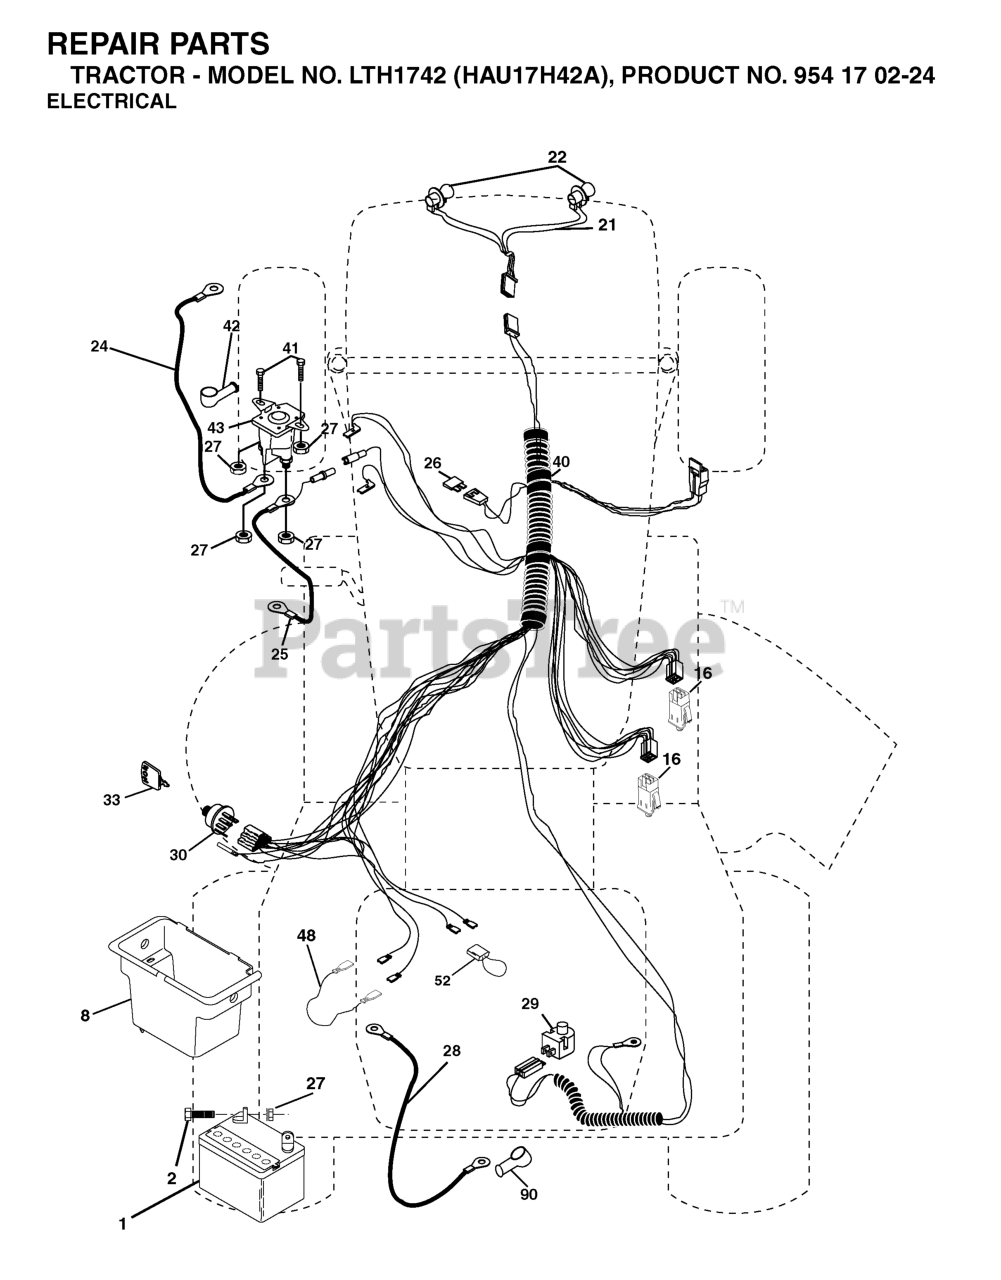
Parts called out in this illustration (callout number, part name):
1	BATTERY 12V .35 AMP
2	BOLT.HEX.1/4.X.3/4.DICHROMATE
8	BOX.BATTERY.FENDER
16	SWITCH INTERLOOK PUSH-IN
21	HARNESS.W/LIGHT SOCKET
24	BATTERY CABLE GT
25	CABLE BATTERY
26	FUSE 20AMP
27	NUT
28	CABLE T
29	RP.SWITCH.PLUNGER.NC.GRAY
30	IGNITION SWITCH
33	KEY MLD GEN DELTA
40	HARNESS.IGNITION
41	BOLT
42	TERMINAL COVER
43	SOLENOID
48	ADAPTER.AMMETER
52	WIRE PROTECTION LOOP
90	COVER TERMINAL
